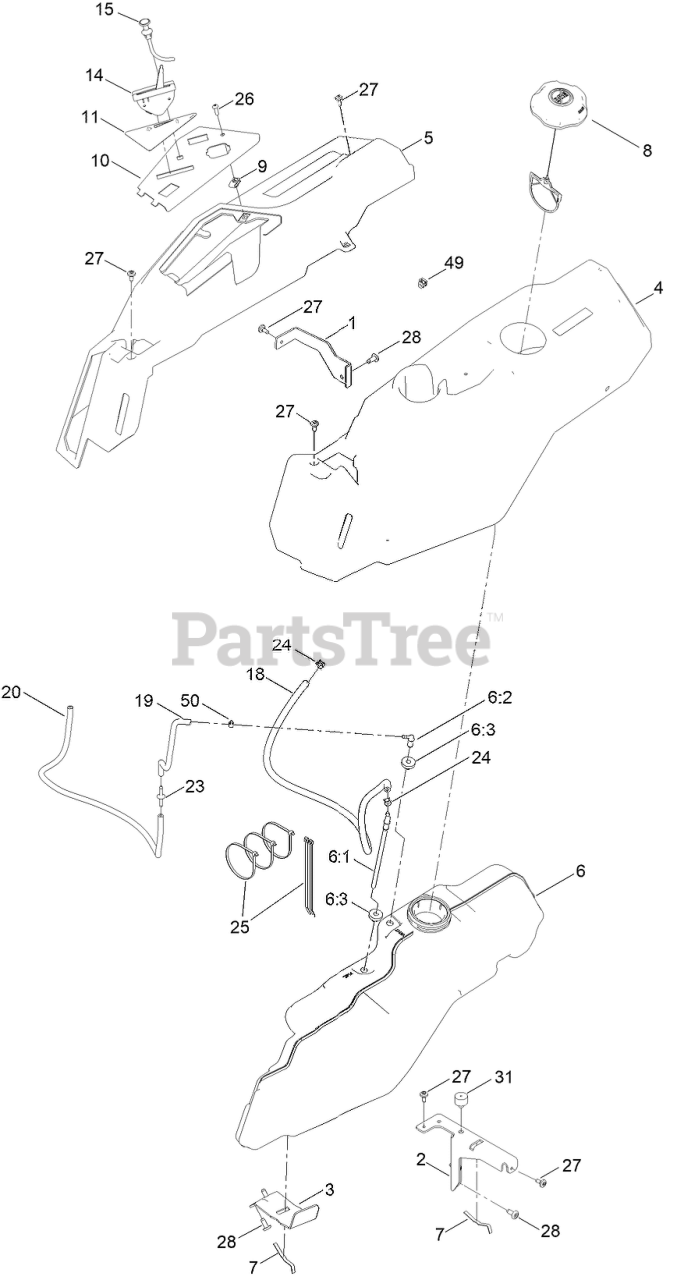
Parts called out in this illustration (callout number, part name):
1	BRACKET-POD
2	SUPPORT-POD, LH
3	SUPPORT-TANK, FUEL
4	POD-LH
5	POD-RH, MYRIDE
6	TANK-FUEL ASM
6:1	CONNECTOR-ELBOW, 90 DEG
6:2	FITTING-ELBOW 90
6:3	BUSHING
7	SPRING
8	CAP-FUEL, RATCHETING
10	PANEL - CONTROL
11	DECAL-PANEL, CONTROL
14	CABLE-THROTTLE
15	CABLE-CHOKE
18	HOSE-FUEL
19	HOSE-FUEL
20	HOSE-FUEL
23	ADAPTER ORIFICE
24	CLAMP-HOSE
25	TIE-CABLE
26	SCREW-PRH
27	SCREW-SHOULDER
31	BUMPER-GROMMET
49	CLIP-HARNESS
50	CLAMP-HOSE
